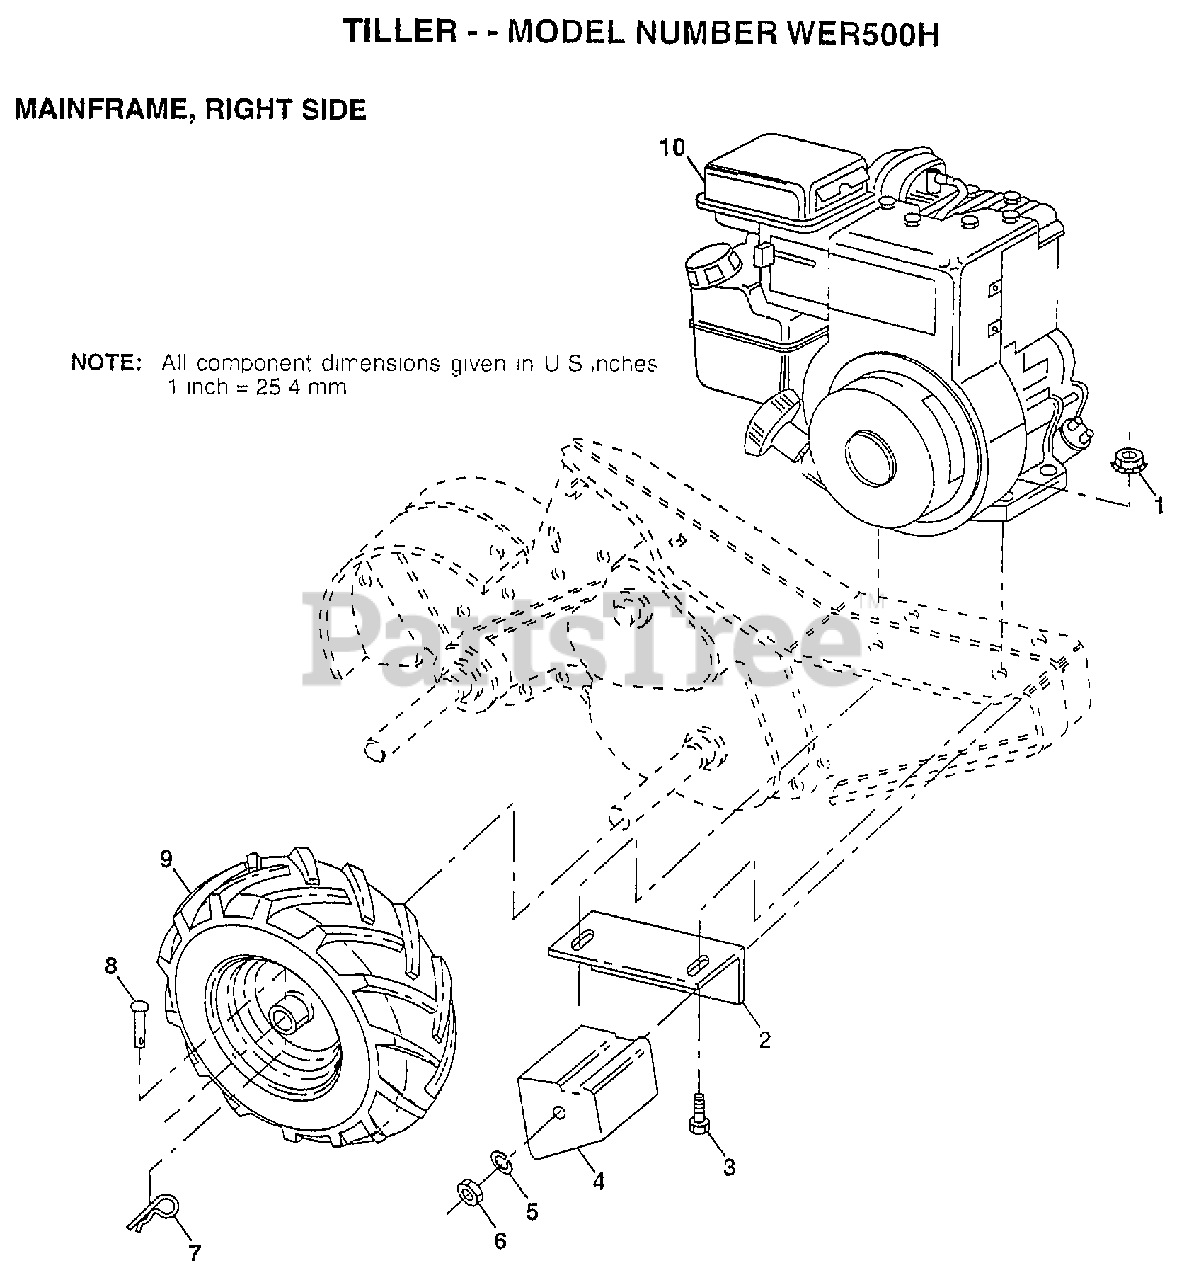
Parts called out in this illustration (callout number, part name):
2	BRACKET RH CRT
3	BOLT.HEX.5/16-1.5
4	COUNTERWEIGHT CRT
5	LOCKWASHER
6	NUT.HEX.3/8-16UNC
7	RETAINER M
8	RIVET.DRILL.1.75
9	TIRE.CHV.13X5.0-6
